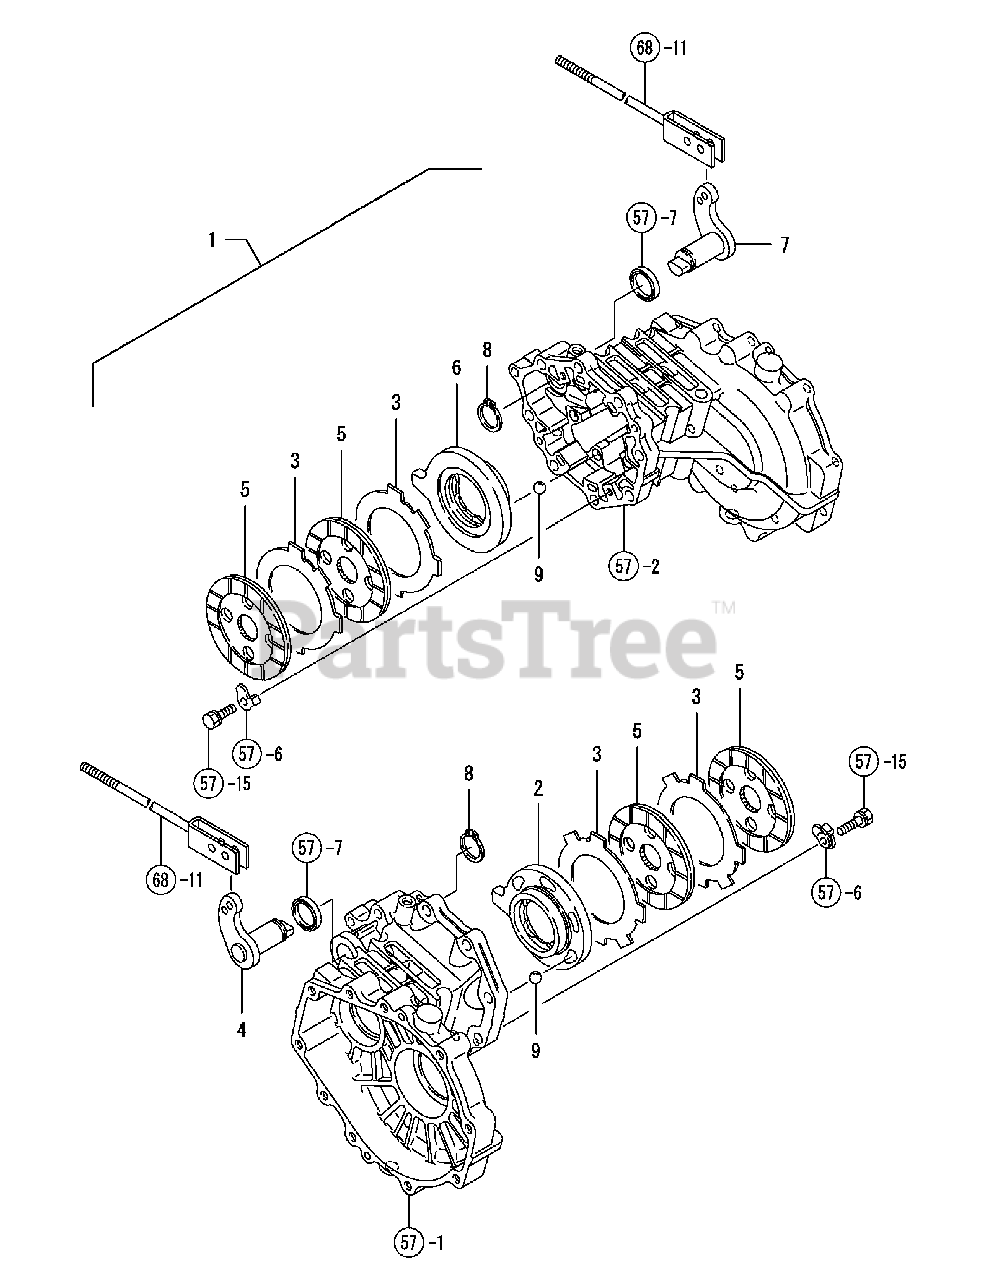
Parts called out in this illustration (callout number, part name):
1	Disk Brake Set,410G
4	Shaft L, Cam Lever
5	Plate 116P Friction
7	Shaft R, Cam Lever
